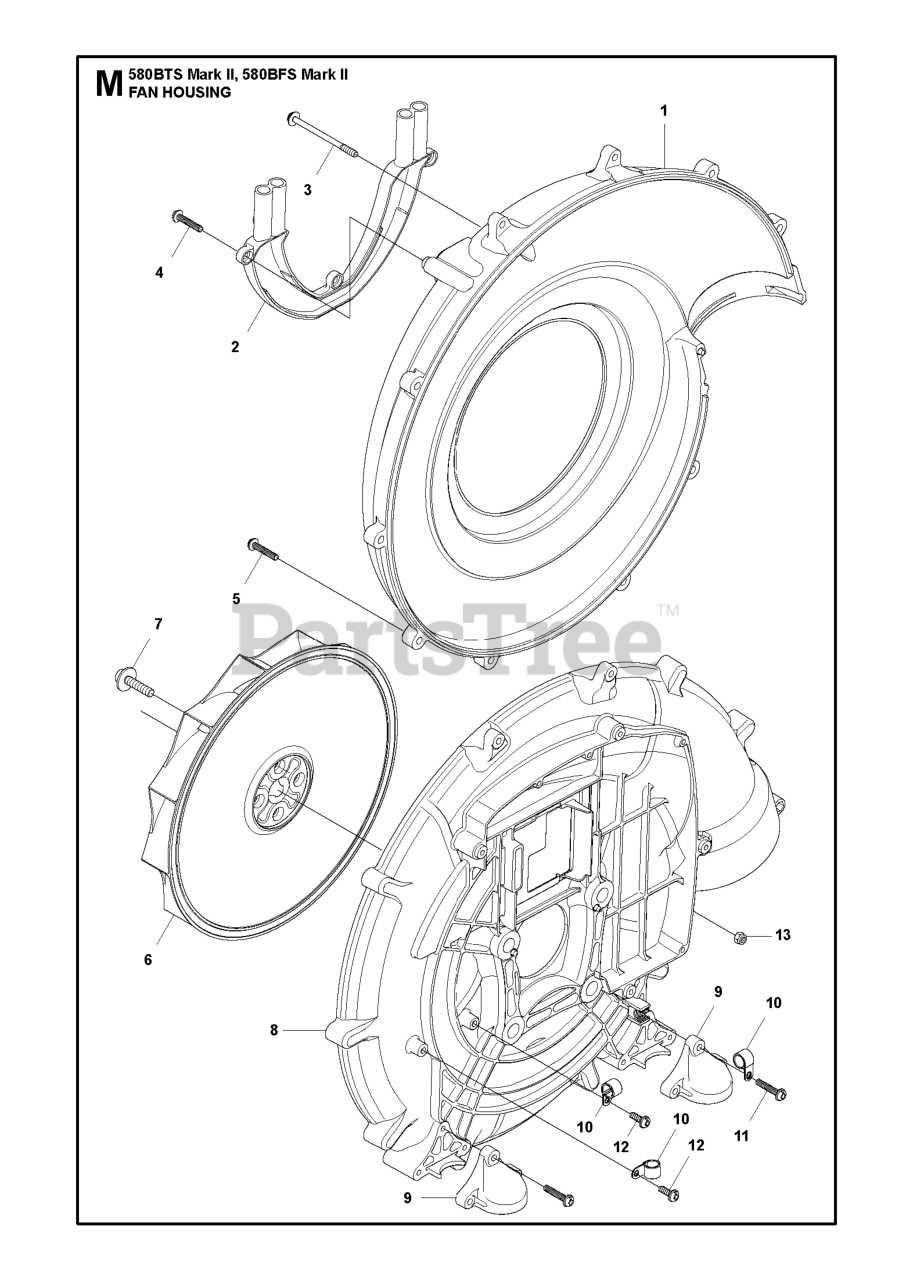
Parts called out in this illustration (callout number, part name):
1	COVER VOLUTE
8	CASE VOLUTE
9	BRACKET DAMPNER
10	CLAMP
13	NUT
